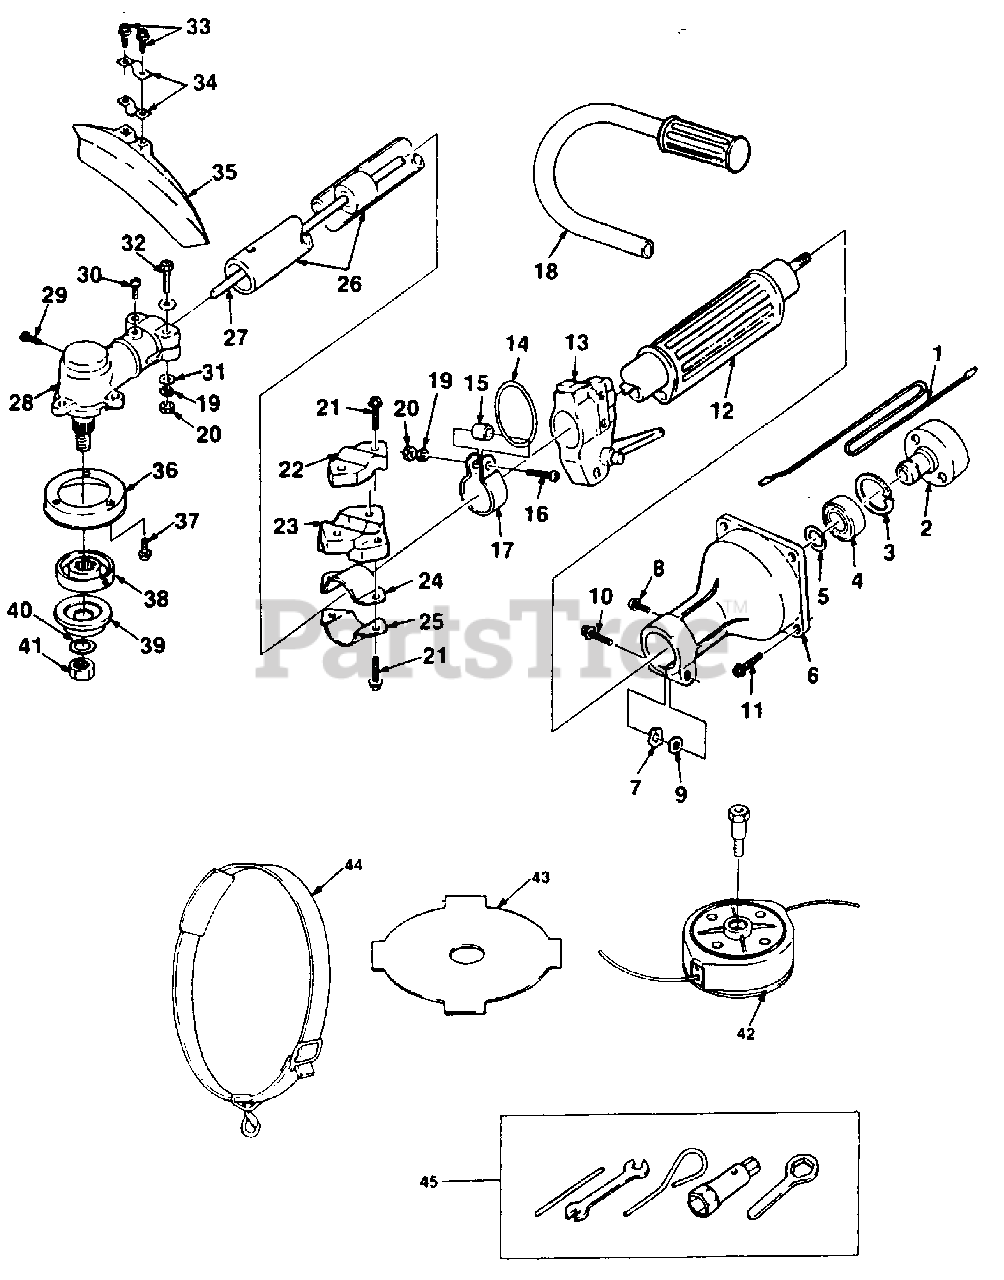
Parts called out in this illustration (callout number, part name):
1	LEAD- Wire
2	DRUM- Clutch
3	RING- Stop
4	BEARING- Ball
5	RING- Stop
6	CASE- Clutch
7	WASHER- Wave
9	WASHER- Flat
13	LEVER Throttle
14	RING- Hanger
18	U-HANDLE
19	WASHER- Spring
20	NUT
22	BRACKET- Top
23	BRACKET- Upper
25	BRACKET- Lower
26	DRIVE SHAFT HOUSING
27	SHAFT- Drive
28	GEAR CASE ASSEMBLY
31	WASHER- Flat
35	DEFLECTOR
38	FLANGE- Upper
39	FLANGE- Lower
40	WASHER- Special
41	NUT- Blade
42	STRING HEAD ASSEMBLY
43	BLADE- Brush (8" 4T accessory)
